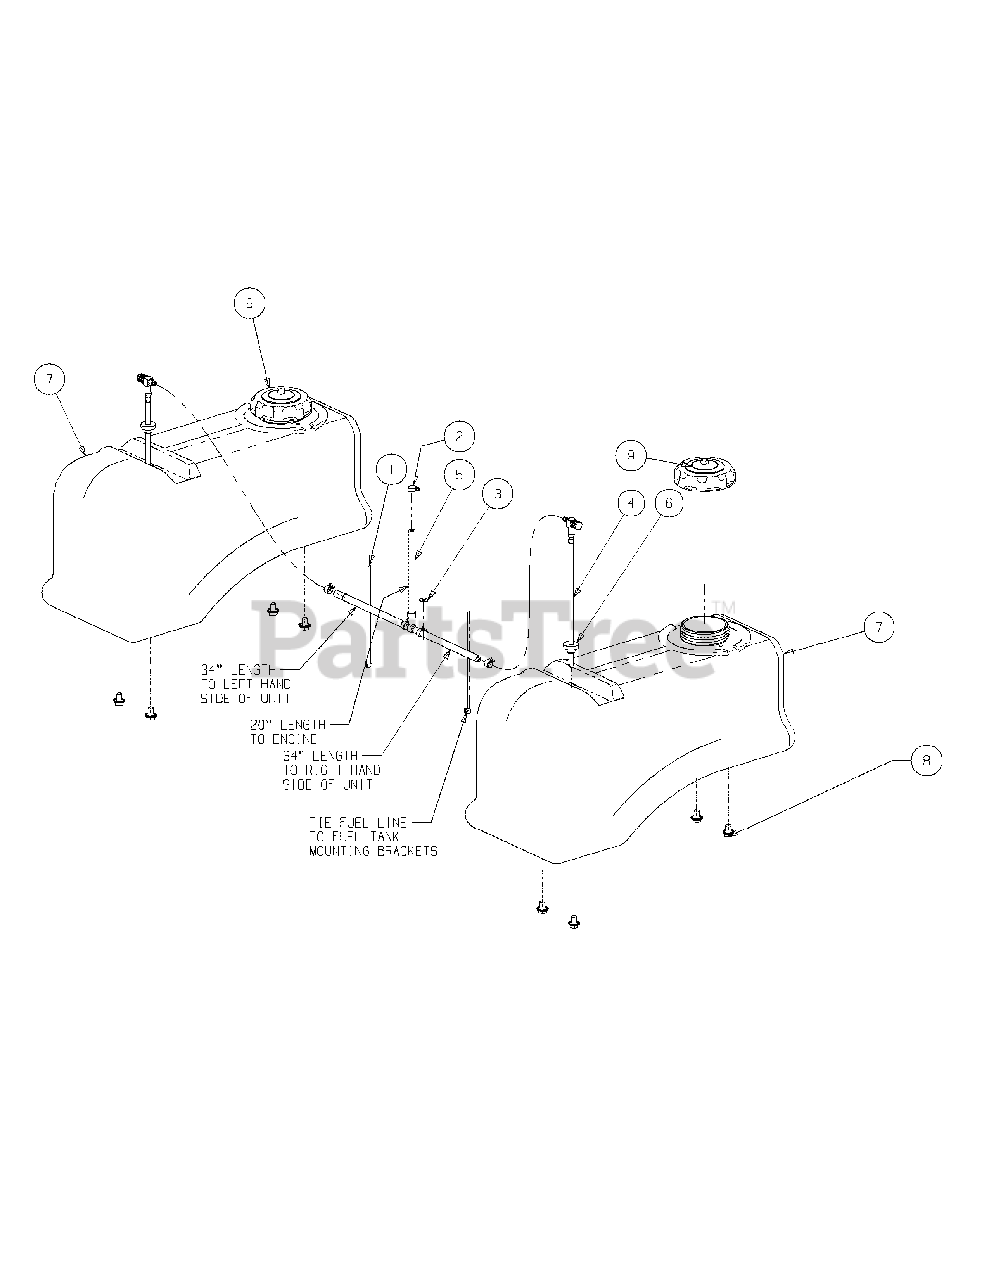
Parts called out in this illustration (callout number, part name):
1	Cable Tie
2	Hose Clamp, SAE #4: 1/4-5/8, SS
3	Flat Washer, 1.4 x .630 x .0515
4	Fuel Fitting
5	Fuel Hose Assembly includes:
5	Hose, 1/4" Fuel Line
5	Clamp, Union
5	Tee Fitting, Fuel
6	Grommet, Fuel Tank
7	Fuel Tank
8	Hex Cap Screw, 3/8-16 x .500
9	Fuel Cap, 3.5
